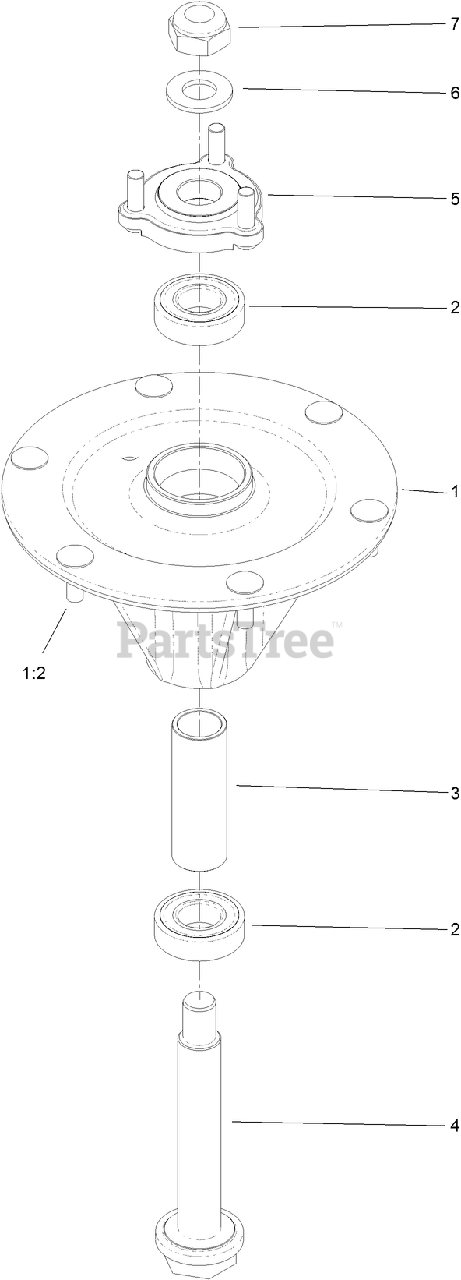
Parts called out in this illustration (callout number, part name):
1	SPINDLE HOUSING ASM W/STUDS
1:2	BOLT-NECK, RIBBED
2	BEARING-BALL
3	SPACER-BEARING
4	SHAFT-SPINDLE, BALL BEARING
5	HUB-SPINDLE (W/STUDS)
6	WASHER
7	NUT-LOCK, NI
